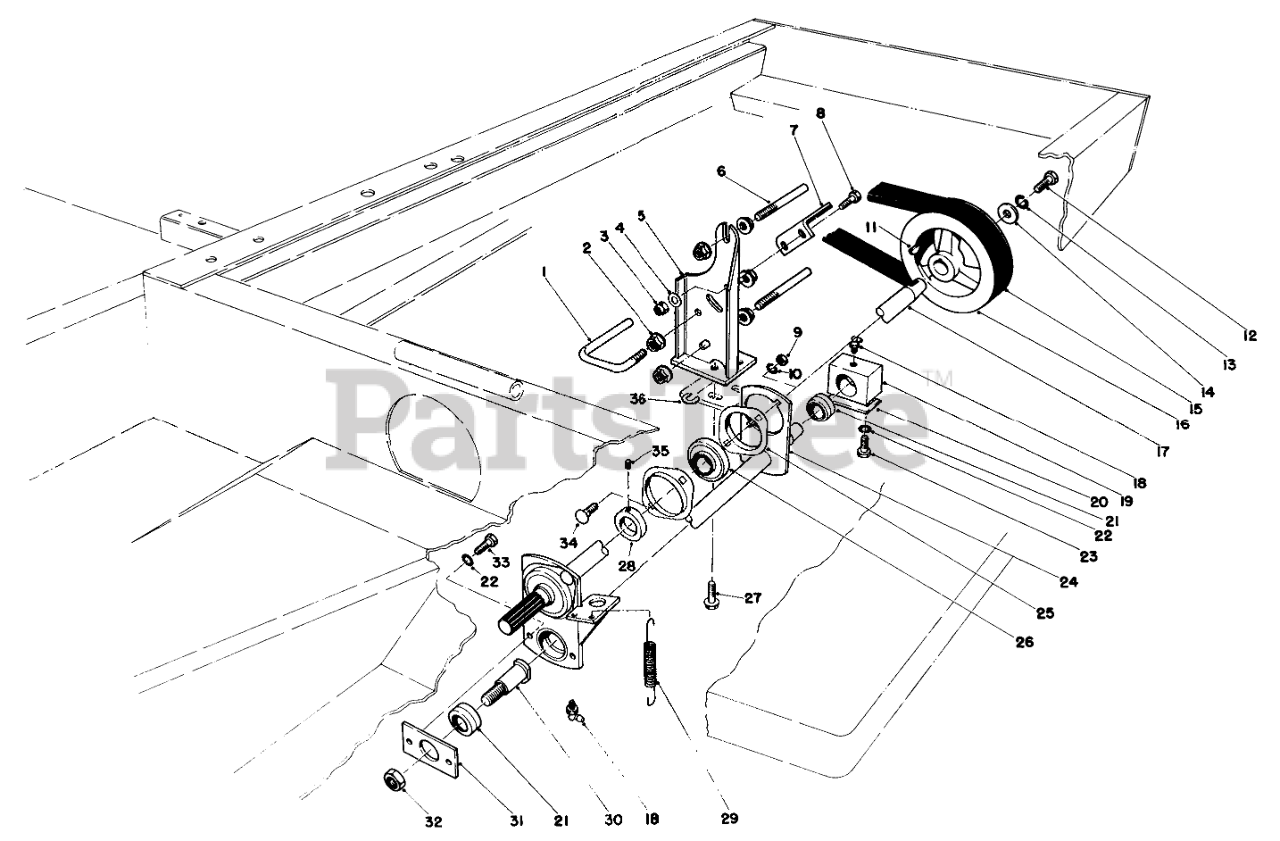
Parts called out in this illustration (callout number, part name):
1	LOWER BELT GUIDE
2	NUT-HHF, WHIZ
3	NUT-LOCK, NI
4	WASHER-PLAIN
5	Bracket-Brake
6	UPPER BELT GUIDE
7	PTO SUPT PAD ASM
8	SCREW-HH
9	NUT-HEX
10	WASHER-LOCK
11	KEY-WOODRUFF
12	SCREW-HH
13	WASHER-LOCK
14	WASHER-FLAT
15	V-BELT
16	Pulley-PTO
17	PTO SHAFT
18	FITTING-GREASE, 90 DEG
19	BEARING HUB PP
20	PTO SHIM BLOCK
21	BEARING
22	WASHER-LOCK
23	SCREW-HH
24	ARM WA - ENGAGE R
25	FLANGE
26	Bearing w/Collar (Incl. Ref. #28 & 35)
27	SCREW-HHF
28	COLLAR-LOCK, BEARING
29	TENSION PTO SPRING R
30	BEARING STUD
31	BRG RETAINER
32	NUT-LOCK, NI
33	SCREW-HH
34	SCREW-CARR
35	SCREW-SET, HSH
36	SPECIAL WASHER
